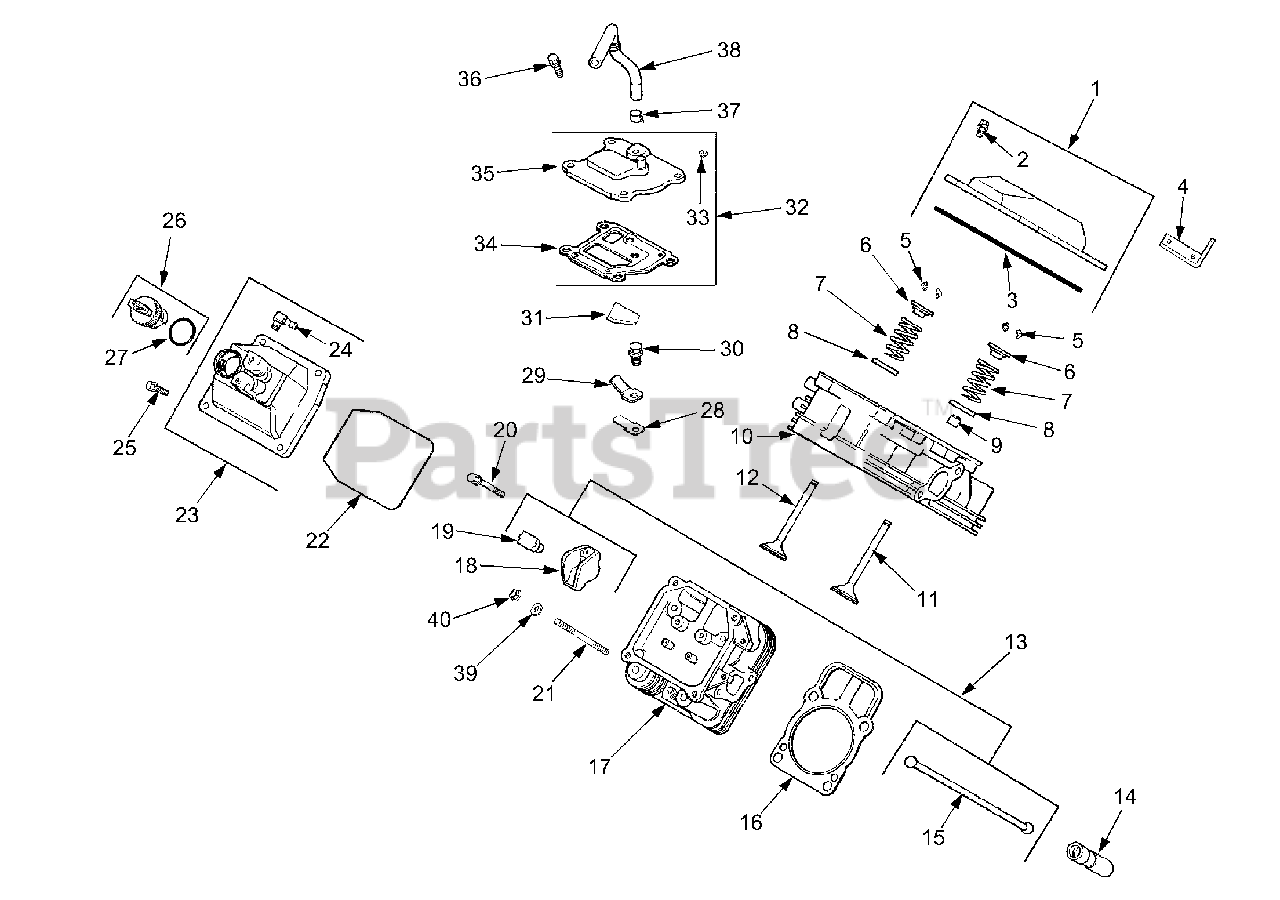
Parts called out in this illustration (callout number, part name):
1	Kit, Valve Cover
2	Screw, Shoulder
3	O-Ring, Valve Cover
4	Strap, Lifting
5	Kit, Retainer
6	Cap, Valve Spring
7	Spring, Valve
8	Retainer, Spring
9	Seal, Valve Stem
10	Head Assembly, #1 Cylinder
11	Valve, Intake (Std.)
12	Valve, Exhaust (Std.)
13	Kit, Valve Train
14	Lifter, Valve
16	Gasket, Cylinder Head
17	Head Assembly, #2 Cylinder
19	Pivot, Rocker Arm
20	Screw, Hex Flange M6 x 1 x 34
21	Stud, Cyl. Hd.
22	O-Ring, Valve Cover
23	Cover, Fuel Pump Valve
24	Connector 90°.
25	Screw, Shoulder
26	Cap Assembly, Oil Fill
27	O-Ring
28	Reed, Breather
29	Retainer, Breather Reed
30	Screw, Hex Flange M5 x 0.8 x 10
31	Filter, Breather
32	Kit, Breather
33	Plug, Allen Head 1/8 NPTF
34	Gasket, Breather
35	Cover, Breather
36	Screw, Hex Flange M6 x 1.0 x 20
37	Clamp, Breather
38	Hose, Breather
39	Washer, Flat, 8mm
40	Nut, Hex Flange, M8 x 1.25
